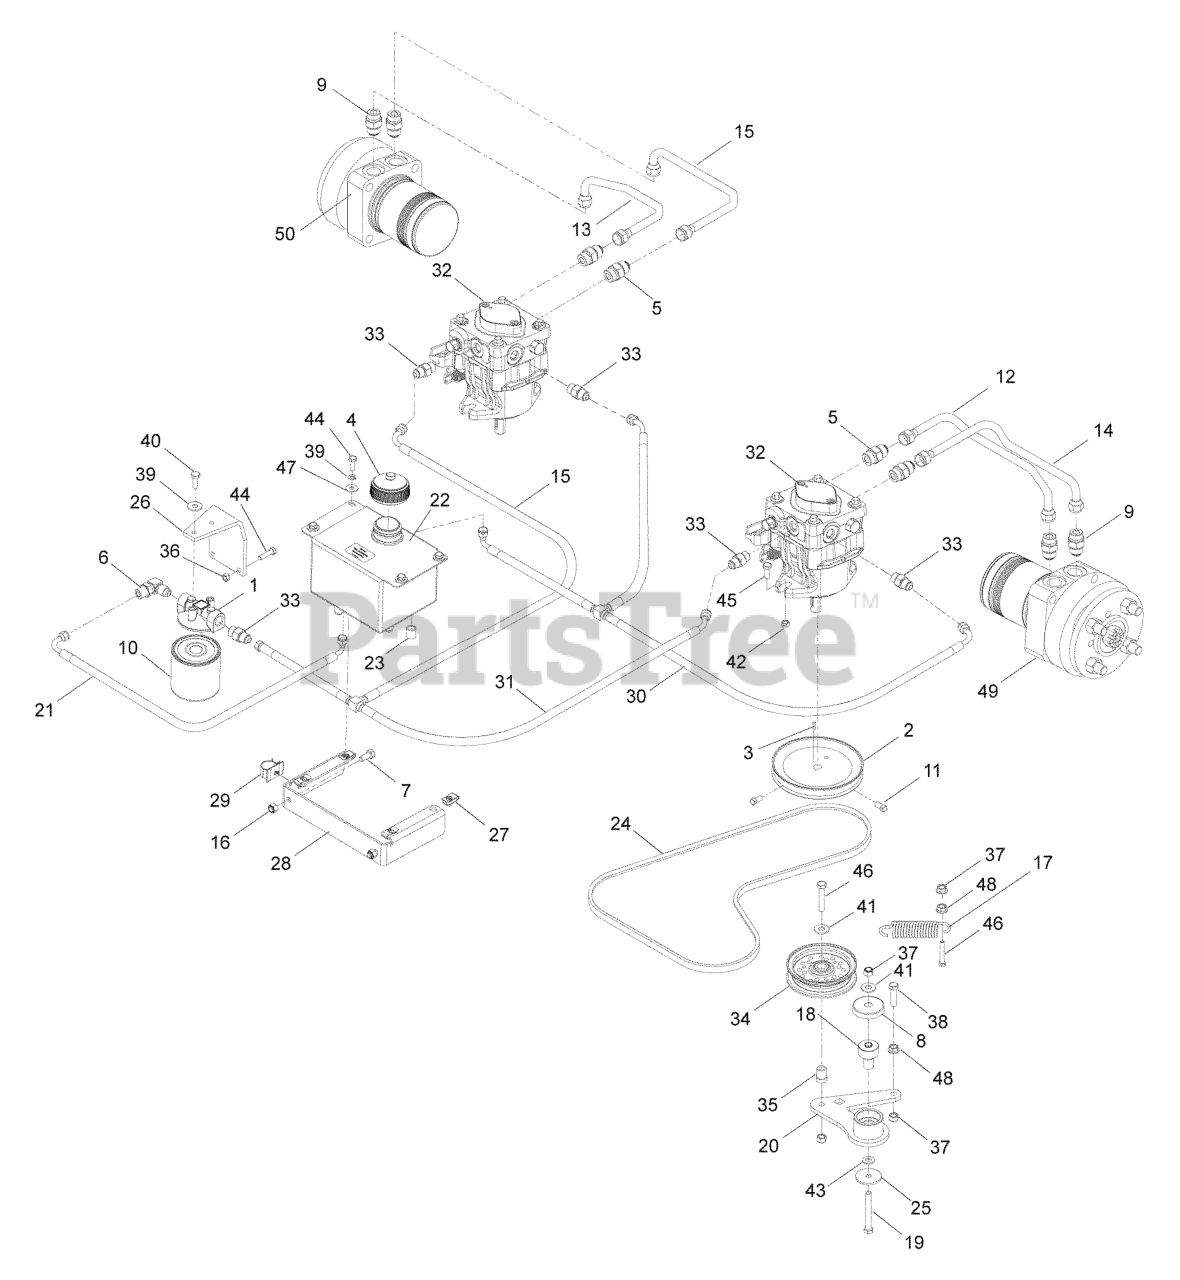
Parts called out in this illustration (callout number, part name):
1	FILTER HEAD
3	KEY 5 MM SQ X 25 MM
4	HYDRAULIC CAP
5	FITTING, STRAIGHT F6400-8-8-0
6	ELBOW, F6801-6-6-0 90 DEGREE
7	HCS 5/16C X 3/4
8	SHIELD, DUST
10	HYDRAULIC OIL FILTER
11	SCREW 5/16C X 5/8 SQ HEAD
12	HOSE, RPA - MA LINE
13	HOSE, RPB - MB, LINE
14	HOSE, LPA - MB LINE
15	HOSE, LPB - MA LINE
16	NUT 5/16 NYLOC
18	PIVOT, BEARING
19	HCS 3/8C X 3
20	ARM, IDLER - W/BEARINGS
21	HOSE, TANK - FILTER LINE
23	NUT 9/16-18 JIC CAP
24	BELT, PUMP
25	WASHER, 3/8 SPEC
26	OIL FILTER BRKT
27	1/4C - U TYPE RETAINER
28	TANK MOUNT
29	PUSH-MOUNT WIRE CLIP
30	HOSE, T-ASM RETURN
31	HOSE, T-ASM SUPPLY
32	HG_PUMP, 10CC W/O FAN
33	HYDRAULIC FITTING
34	IDLER PULLEY
35	BUSHING, IDLER FLANGE
36	NUT.1/4-20.HEX.NYLOC.ZD
37	NUT 3/8-16 NYLOC
38	HCS 3/8C X 1 1/2
39	LOCKWASHER 1/4"
40	HCS 1/4C X 5/8
41	WASHER 3/8 FLAT
42	NUT 3/8C CENTERBLOCK
43	WASHER 3/8 SAE FLAT
44	HCS 1/4C X 3/4 HCS
45	4CS 3/8C X 1 SERRATED HEAD
46	HCS 3/8C X 2
47	WASHER 1/4 FLAT
48	NUT 3/8C WHIZ
49	TL15 WHEEL MOTOR
